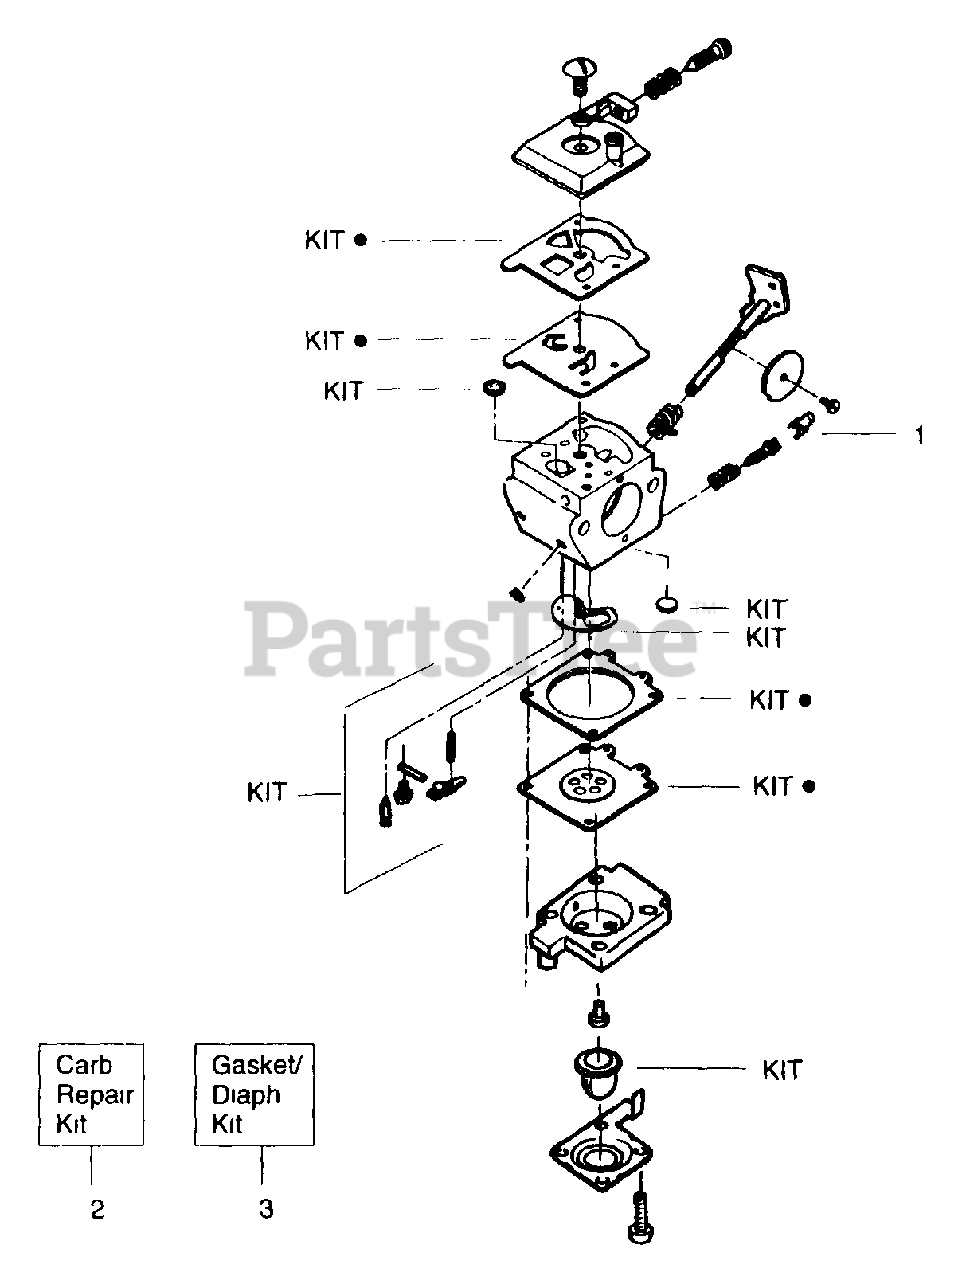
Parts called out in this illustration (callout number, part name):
1	Limiter Cap
2	Carburetor Repair Kit
3	Gasket/Diaphragm Kit
